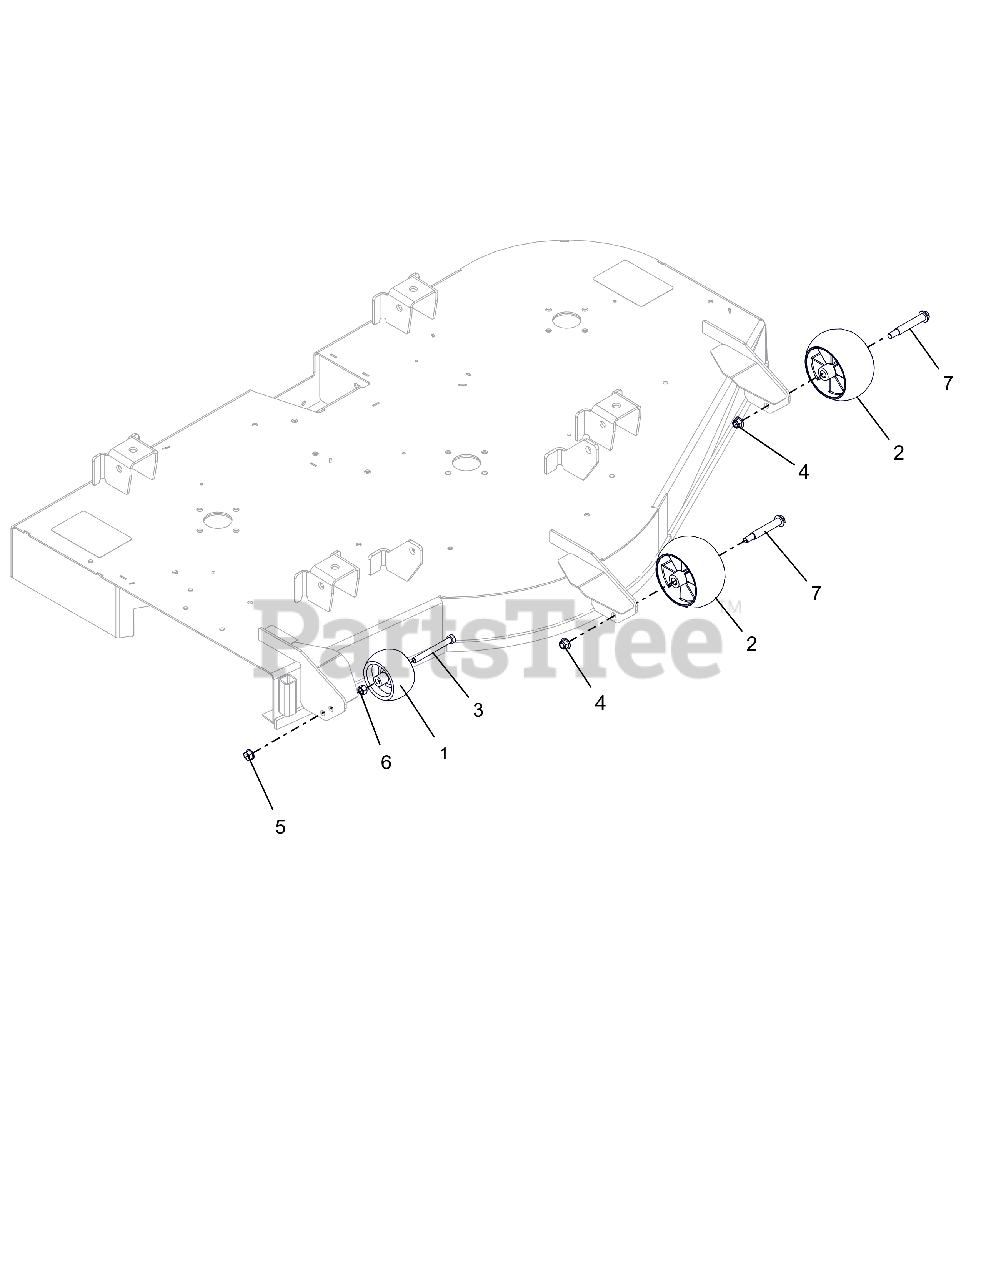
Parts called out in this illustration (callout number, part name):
2	ANTI-SCALP WHEEL - 5X OS
3	@BLT-HEX .38-16X3.50 GR5 YWZC
4	NUT,NYL-FLG .38-16 GF ZCC
5	NUT-LK-TOP-FLG .38-16 ZC120
6	@NUT-HEX .38-16 YWZC
7	BLT-SHLDR .38-16X2.50 HWH G5
